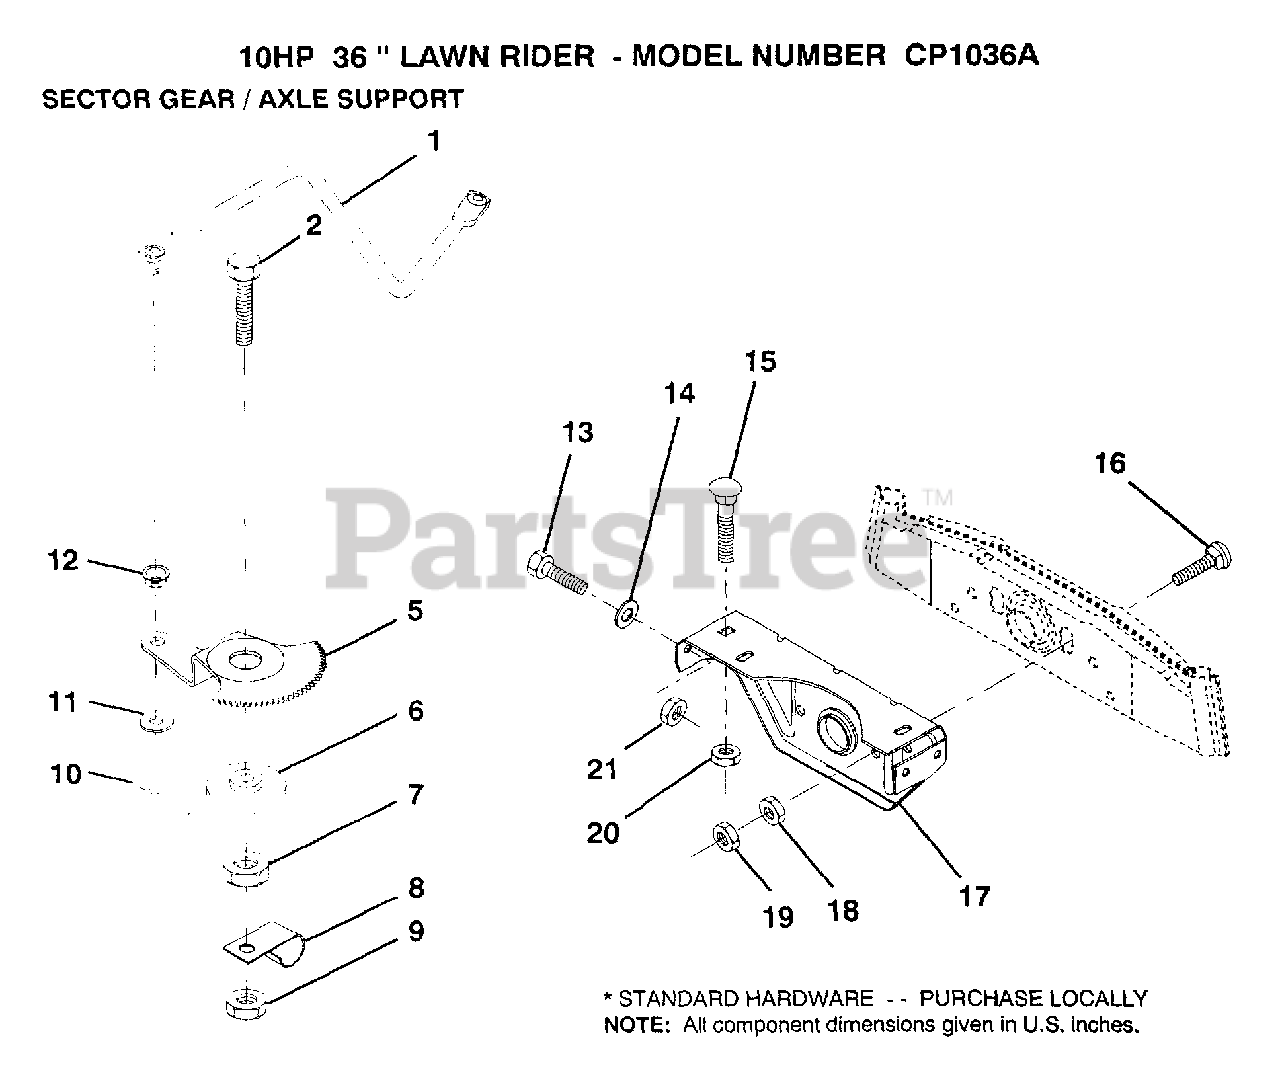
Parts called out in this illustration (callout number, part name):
1	DRAG LINK
2	"BOLT,HEX"
5	GEAR SECTOR
6	BUSHING
7	NUT
8	CLIP INSULATOR
9	NUT LTV
10	COTTER PIN
11	WASHER
12	BUSHING.DRAGLINK
13	BOLT
14	WASHER
15	BOLT
16	BOLT
17	"SUPT,FRT AXLE"
18	NUT.HEX.3/8-16UNC
19	LOCKNUT
